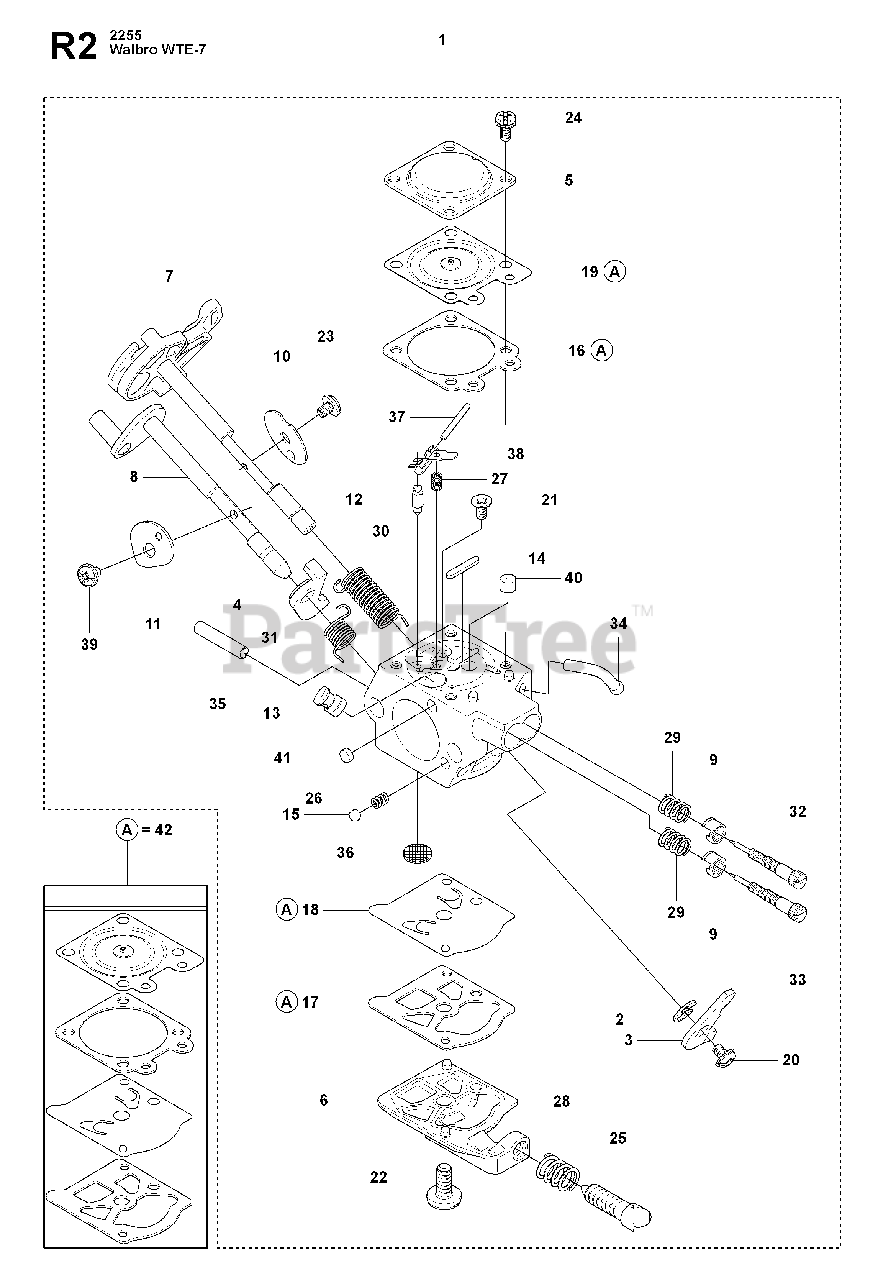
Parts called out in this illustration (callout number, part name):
1	CARBURETOR
2	E CLIP
5	DIAPHRAGM COVER
9	LIMITER CAP
12	INLET NEEDLE
13	NOZZLE ASSY
18	DIAPHRAGM, FUEL PUMP
19	DIAPHRAGM
23	SCREW
24	SCREW W/ WASHER
32	NEEDLE
33	NEEDLE
36	FUEL INLET SCREEN
37	FULCRUM PIN
41	PLUG WELCH
42	KIT
